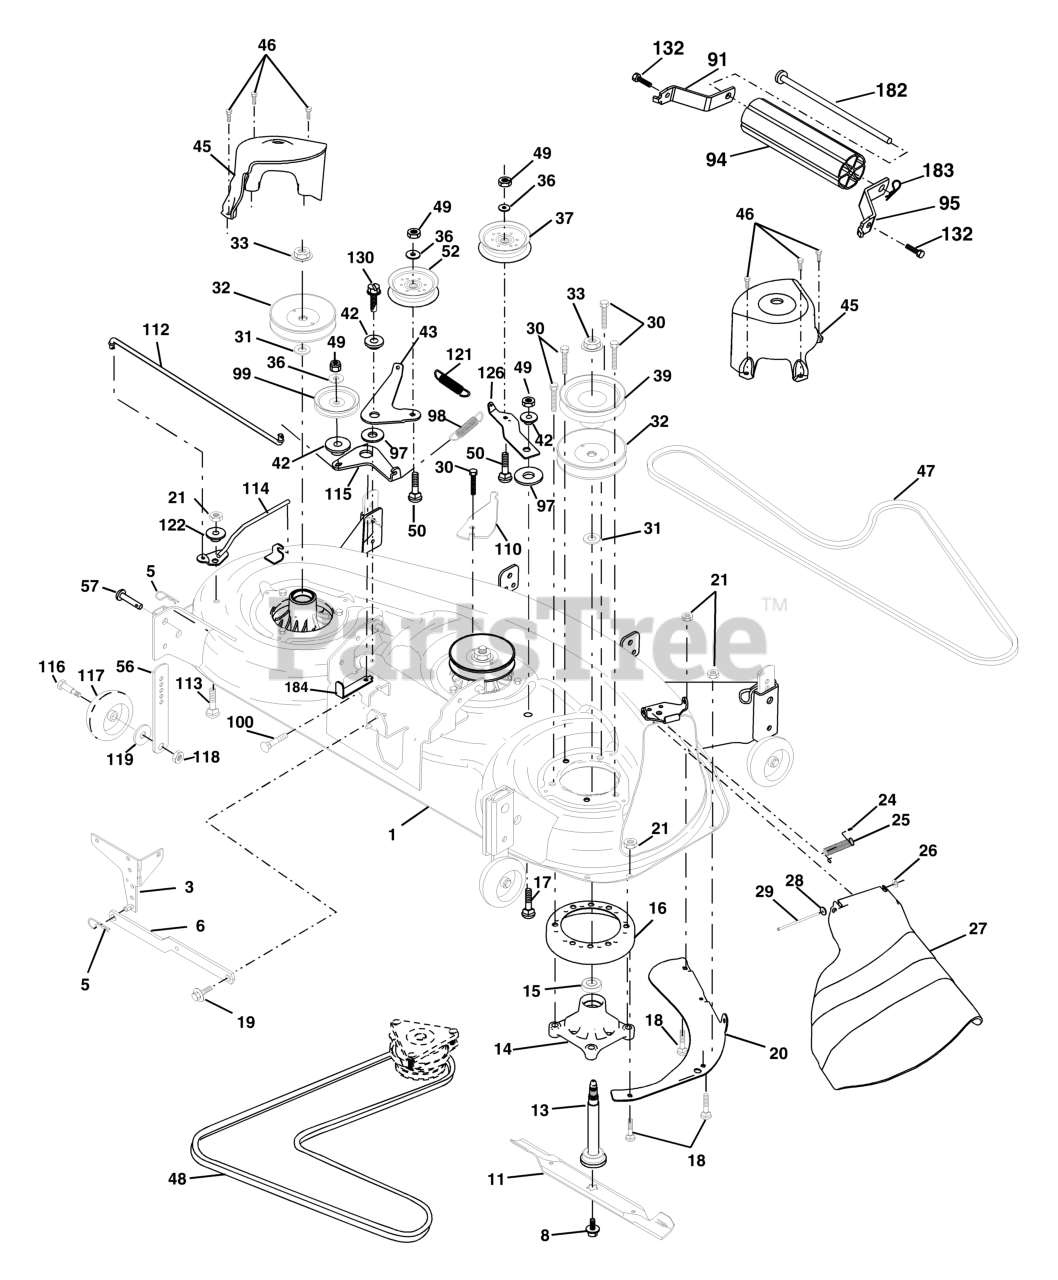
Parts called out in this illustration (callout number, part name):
1	DECK WELDMENT
3	BRACKET ASM.
5	RETAINER-SPRNG RB
6	BAR SWAY DECK
8	BOLT 7/16 ASM BLADE
11	48" HI-LIFT BLADE
13	SHAFT ASM W/LOWER BEARING
14	HOUSING, MANDREL 48"
16	STRIPPER.MANDREL.ROUND.BLACK
17	BOLT
18	BOLT
19	BOLT SHD 5/16-18
20	BAFFLE, VORTEX MWR
21	LOCKNUT
24	CAP-SLEEVE LT
25	SPRING, TORSION
26	NUT PUSH M
27	DEFLECTOR SUBS TO 532 180655
28	Washer 11/32 x 5/8 x 16 Ga.
29	ROD.HINGE
30	SCREW, WASHER HEAD
31	WASHER
32	PULLEY, MANDREL
33	NUT, FLG TOPLOCK 9/16"
36	WASHER
37	PULLEY.IDLER.FLAT
39	PULLEY.DRIVEN.DECK.48'
42	SPACER.RETAINER.MOWER
43	ARM, IDLER SECONDARY
45	COVER, MANDREL DECK
46	SCREW.1/4-20X5/8
47	V-BELT, 48"SECONDARY
48	V-BELT PRIMARY 48"
50	BOLT.3/8-16X1.50
52	PULLEY.IDLER.FLAT.46.PR.DR.
56	BAR.ADJUST.WHEEL.ANTI.SCALP.BL
57	RIVET.PIN.HEAD.YELLOW.
91	BRKT.NOSEROLLER.LH.48"
94	NOSE ROLLER 48"
95	BRKT.NOSEROLLER.RH.48"
97	HARDENED WASHER
98	SPRING PRIMARY DRIVE
99	PULLEY,IDLER"V"
100	BOLT
107	BAFFLE.VAC.EDGE.MOWER.48"
108	BOLT
109	NUT.CROWNLOCK.1/4
110	ARM, SPRING SECONDARY
112	LEVER, TENSION RELIEF LINK
113	BOLT CRT
114	LEVER ASM, TENSION RELIEF
115	ARM, SPRING TENSION RELIEF
116	BOLT, SHOULDER
117	RP WHEEL. GUAGE RALLY
118	LOCKNUT
119	WASHER.5/16.FLAT.STE.STD.
121	SPRING.DRIVE.SECONDARY.48".DEC
122	BUSHING, PIVOT TENSION RELIEF
126	ARM, IDLER PRIMARY DECK
130	SCREW 3/8-16X1
182	ROD.ROLLER.NOSE.NARROW.48"
183	SPRING RETAINER
184	KEEPER BELT IDLER PLATED
